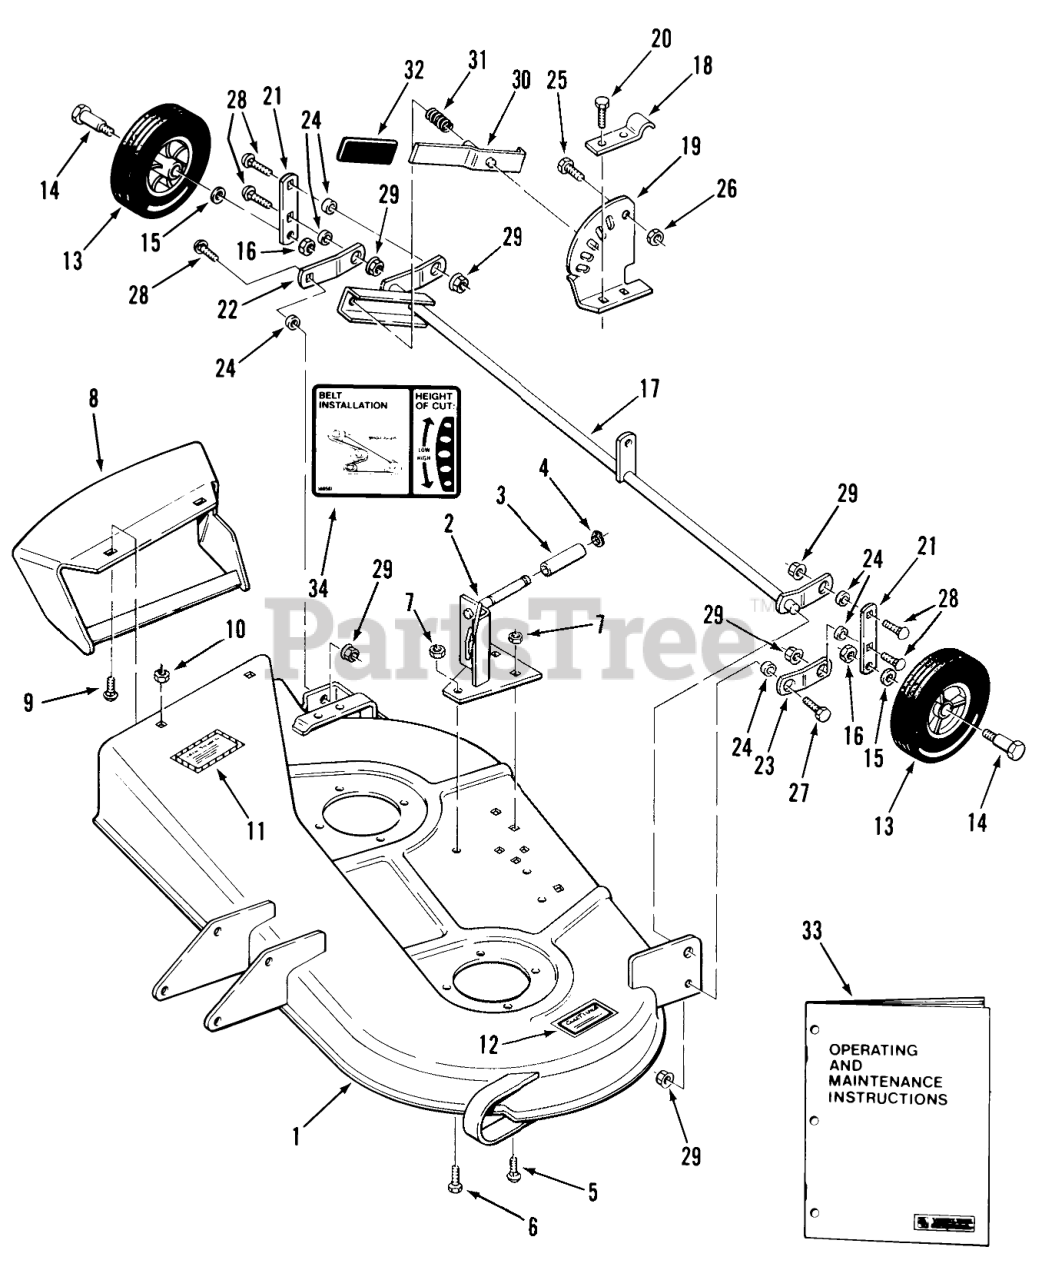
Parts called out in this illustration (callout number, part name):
1	Mower Deck
2	Rear Hanger Support
3	SPACER
4	Snap Ring
5	CARRIAGE BOLT -9
6	Bolt
7	Nut
8	ASSY-CHUTE EXT R
9	CARRIAGE BOLT -4
10	Nut
11	DECAL
12	Caution Decal
13	WHEEL-GAUGE
15	WASHER
16	Nut
17	Gage Wheel Support
18	Pivot Bracket
19	Quadrant
20	Bolt
21	LINK R
22	ARM-PIVOT RH R
23	Arm LH
24	SPACER
26	Nut
27	BOLT
28	Bolt
29	LOCKNUT-FLANGE
30	Lever
31	SPRING-COMPRESSION
33	Operating and Maintenance Instructions
34	DECAL-BELT&HEIGHT
